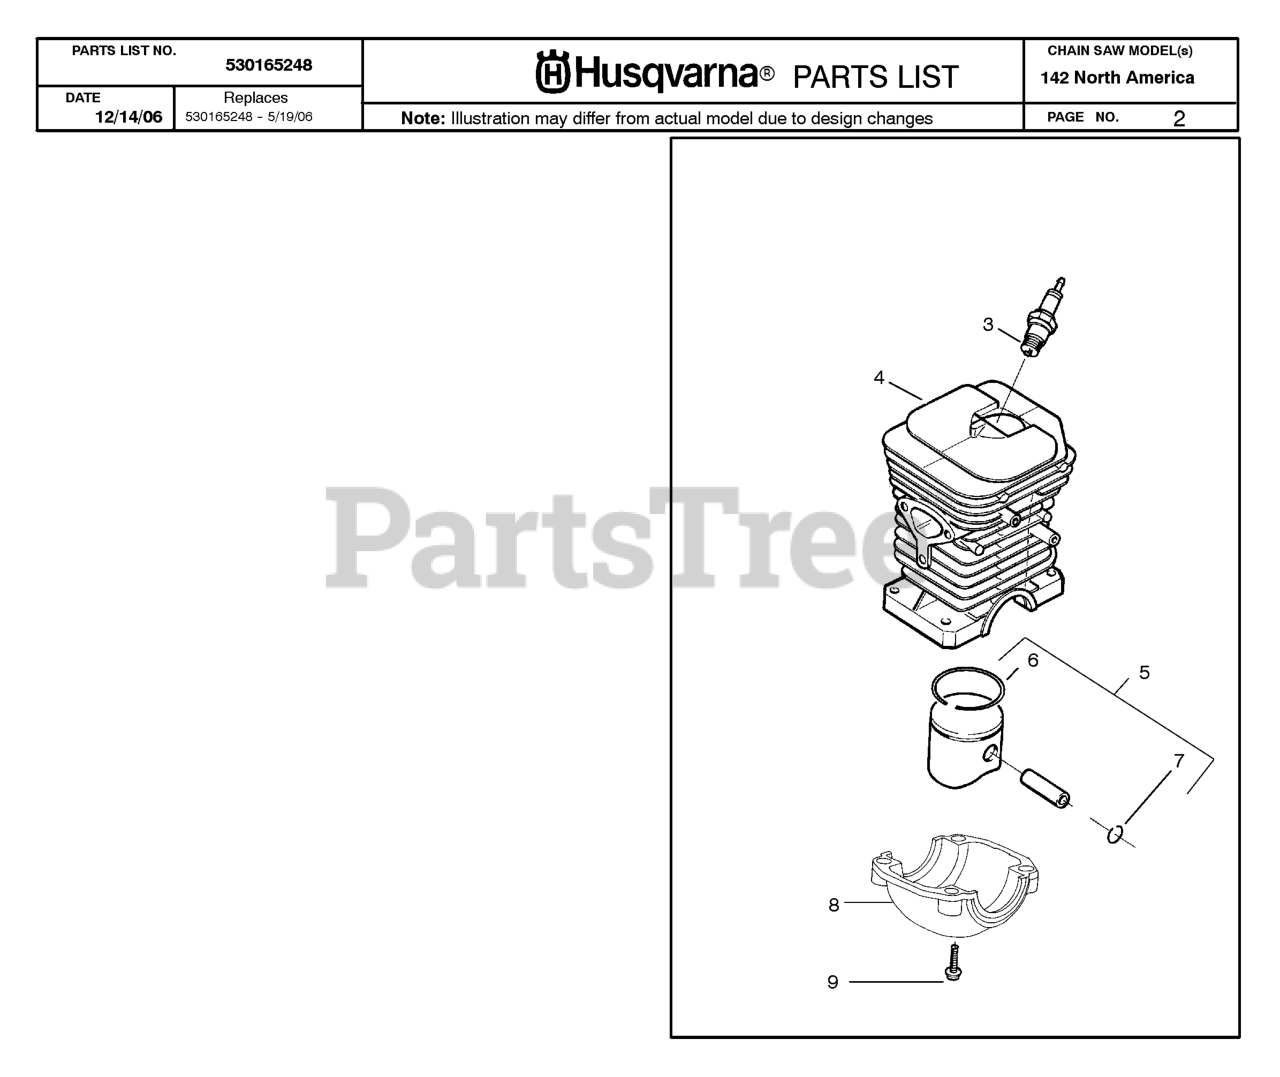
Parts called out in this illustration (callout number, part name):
3	Spark Plug (RCJ--7Y)
4	CYLINDER ASSY/141
5	KIT-PISTON
6	PISTON RING HV41
7	C-CLIP,PSTN PIN 36/41
8	CAP-CRANKSHAFT
9	SCREW-M5-0.8 X 25MM(TAP)
